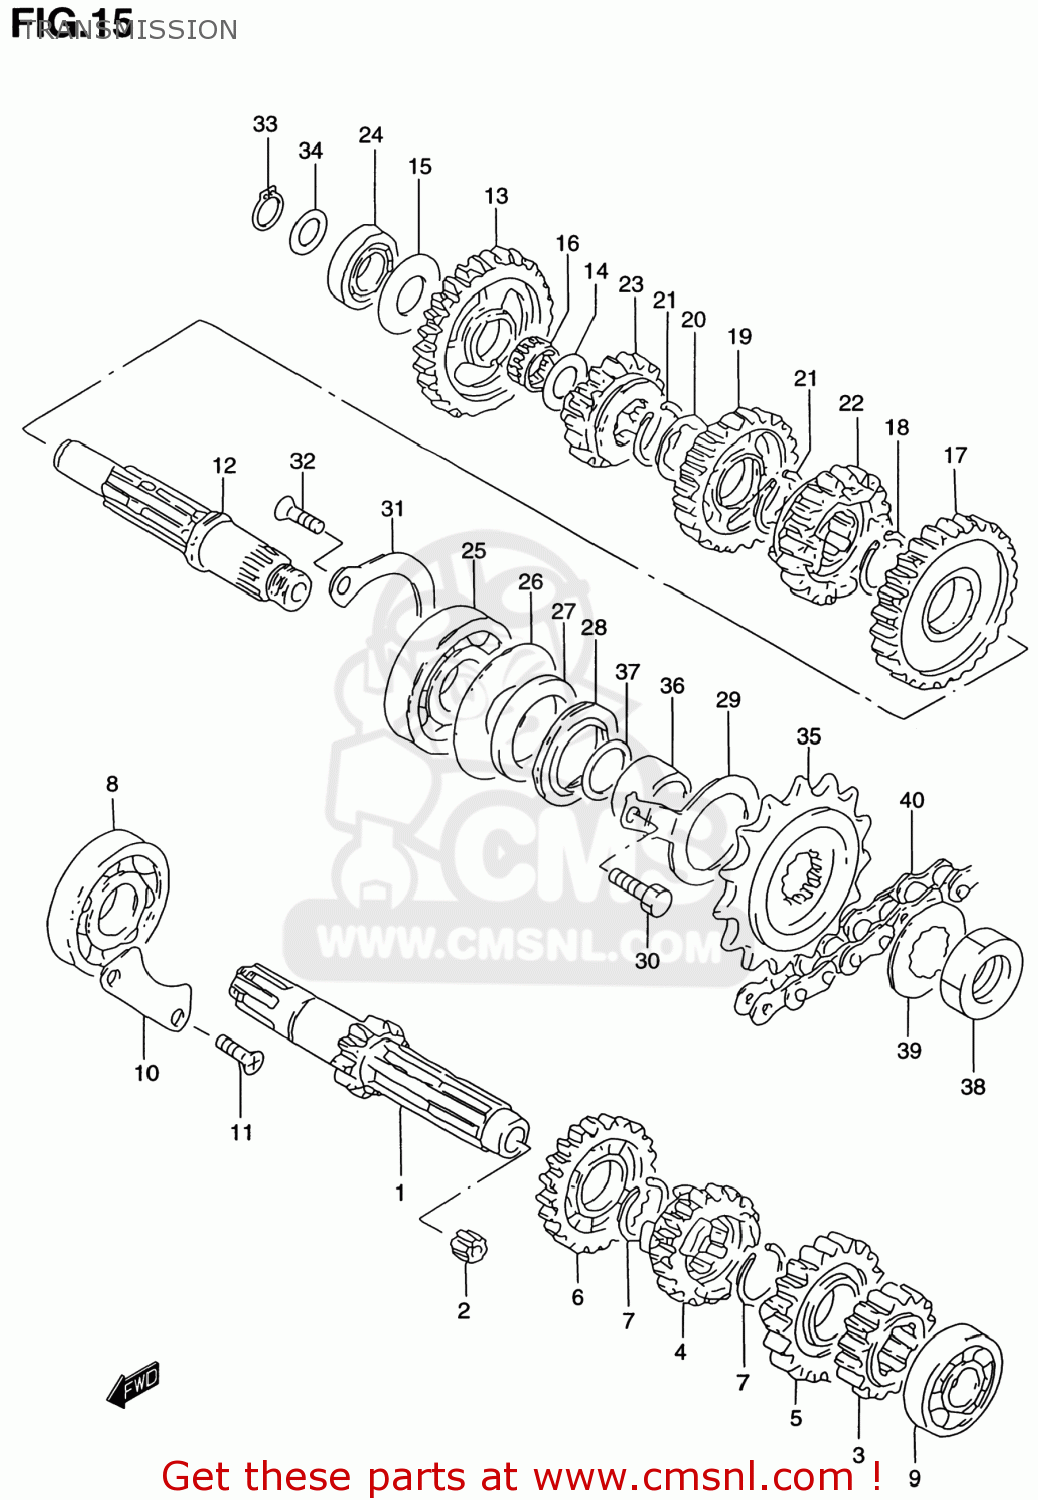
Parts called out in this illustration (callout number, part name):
1	SHAFT,COUNTER (NT:11)
2	BUSH
3	GEAR,2ND DRIVE(NT:16)
4	GEAR,3RD DRIVE(NT:19)
5	GEAR,4TH DRIVE(NT:20)
6	GEAR,FIFTH DRIVE (NT:22)
7	CIRCLIP
8	BEARING(22X56X16)
9	BEARING(17X40X12)
10	RETAINER,CNTR SHAFT BEARING
11	SCREW
12	SHAFT,DRIVE
13	GEAR,1ST DRIVEN(NT:29)
14	SHIM(17X28X1)
15	WASHER
16	BEARING(17X21X9.8)
17	GEAR,2ND DRIVEN(NT:27)
18	CIRCLIP
19	GEAR,3RD DRIVEN(NT:24)
20	WASHER,LOCK
21	CIRCLIP
22	GEAR,4TH DRIVEN(NT:20)
23	GEAR,5TH DRIVEN(NT:18)
24	BEARING(17X36X12)
25	BEARING(22X56X16)
26	WASHER(35X55X1)
27	OIL SEAL (30X43X5)
28	OIL SEAL (30X43X7)
29	RETAINER,DRIVE SHAFT OIL SEAL
30	BOLT
31	RETAINER,DRIVE SHAFT BEARING
32	SCREW
33	CIRCLIP,17MM
34	SHIM(17X24X1)
35	SPROCKET,ENGINE(NT:15)
36	SPACER
37	O RING(D:2.5,ID:21)
38	NUT
39	WASHER,LOCK
40	CHAIN(DID520VC5,110LE)
